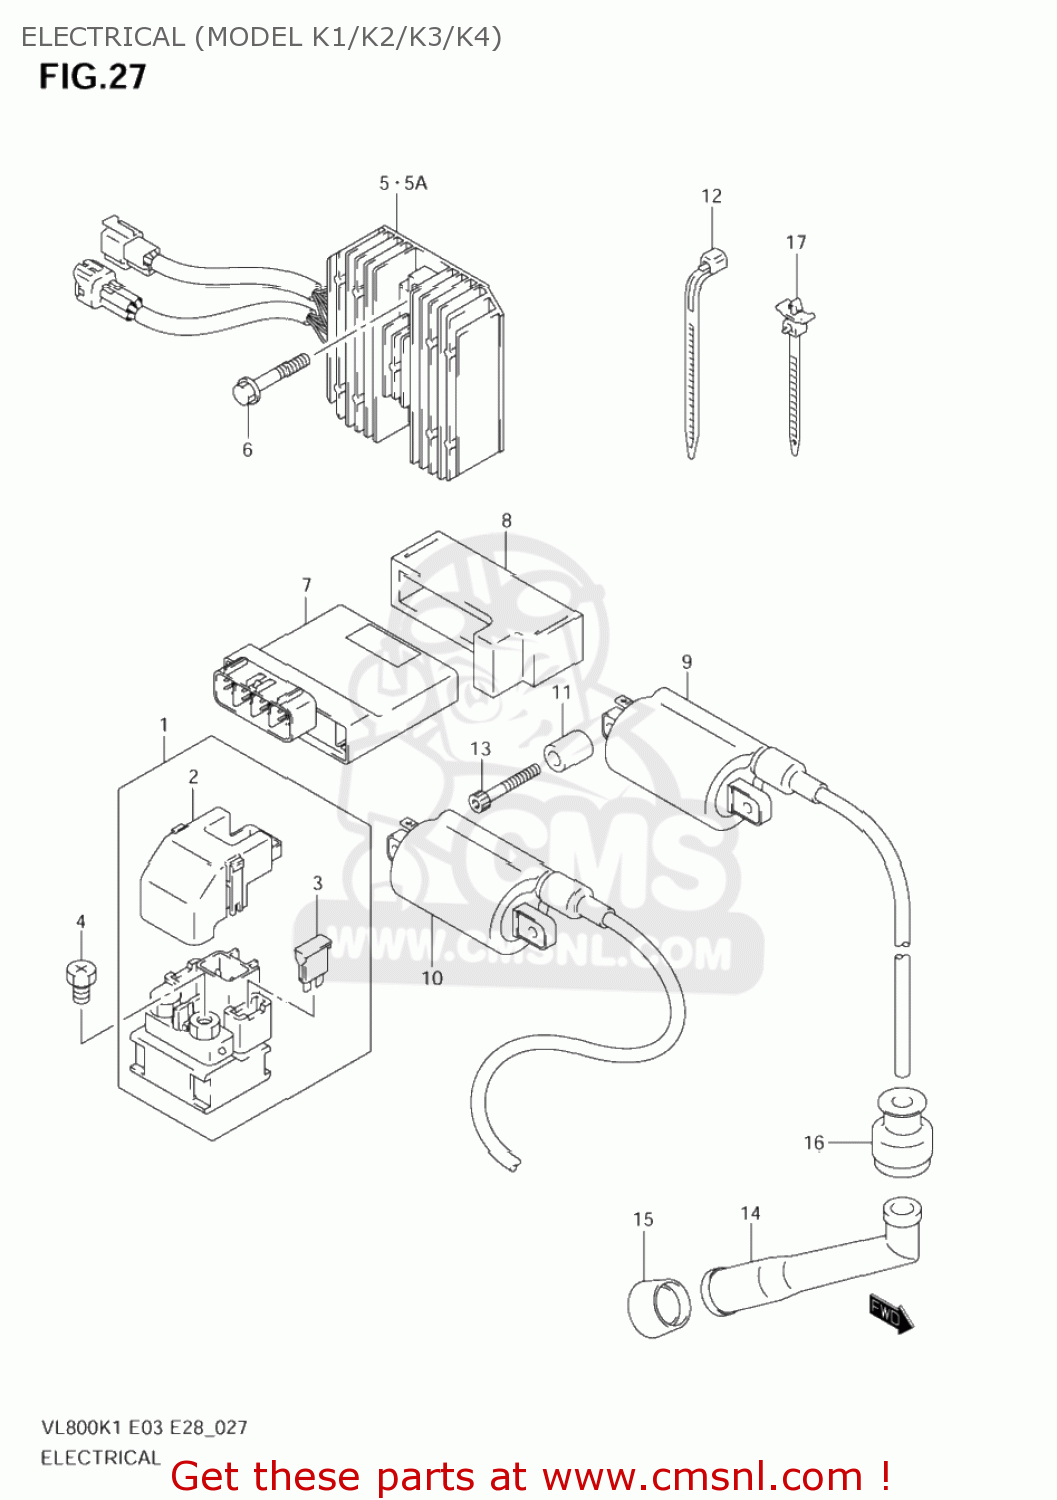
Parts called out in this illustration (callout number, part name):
1	RELAY ASSY,STARTING MOTOR
2	COVER,RELAY ASSEMBLY
3	FUSE(30A)
4	SCREW(6X8)
5	RECTIFIER ASSY
5A	RECTIFIER ASSY
6	BOLT(6X23)
7	IGNITOR ASSY
8	COVER,IGNITOR
9	COIL ASSY,IGNITION
10	COIL ASSY,IGNITION
11	SPACER(6.2X12X16)
12	CLAMP(L:165)
13	BOLT
14	CAP,SPARK PLUG
15	SEAL,SPARK PLUG CAP
16	SEAL,HIGH TENSION CORD
17	CLAMP(L:90)
